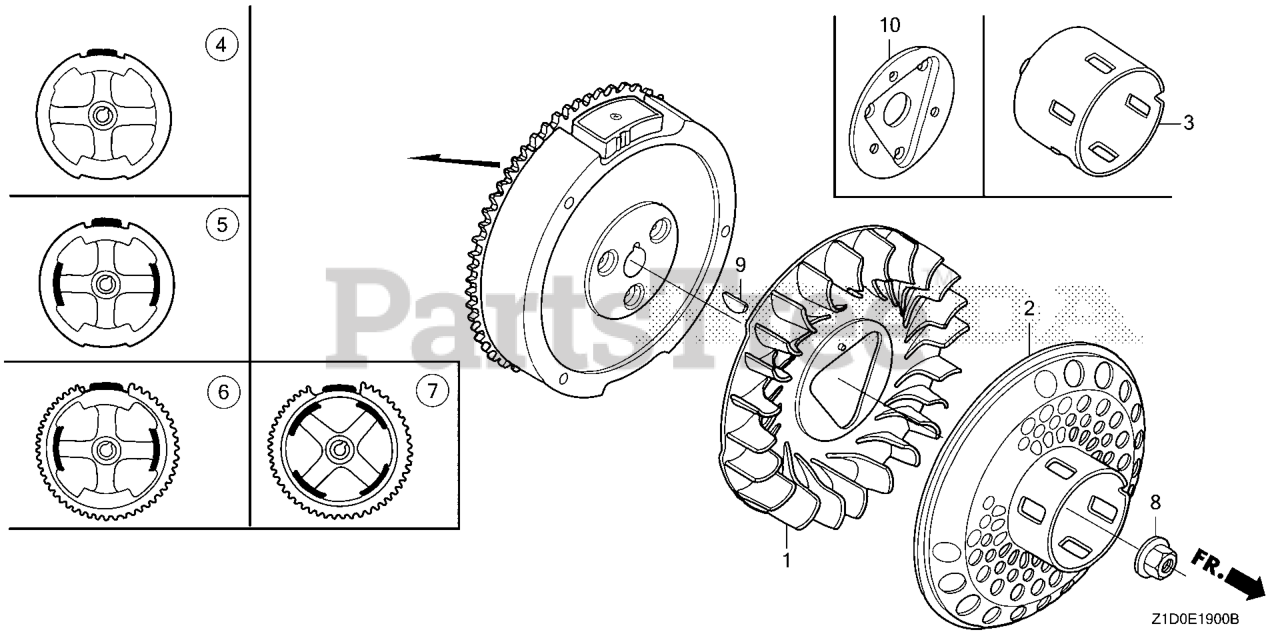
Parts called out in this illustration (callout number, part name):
1	FAN, COOLING
2	PULLEY, STARTER (SCREEN GRID)
8	NUT, SPECIAL (16MM) (1)
9	KEY, SPECIAL WOODRUFF (25X18)
